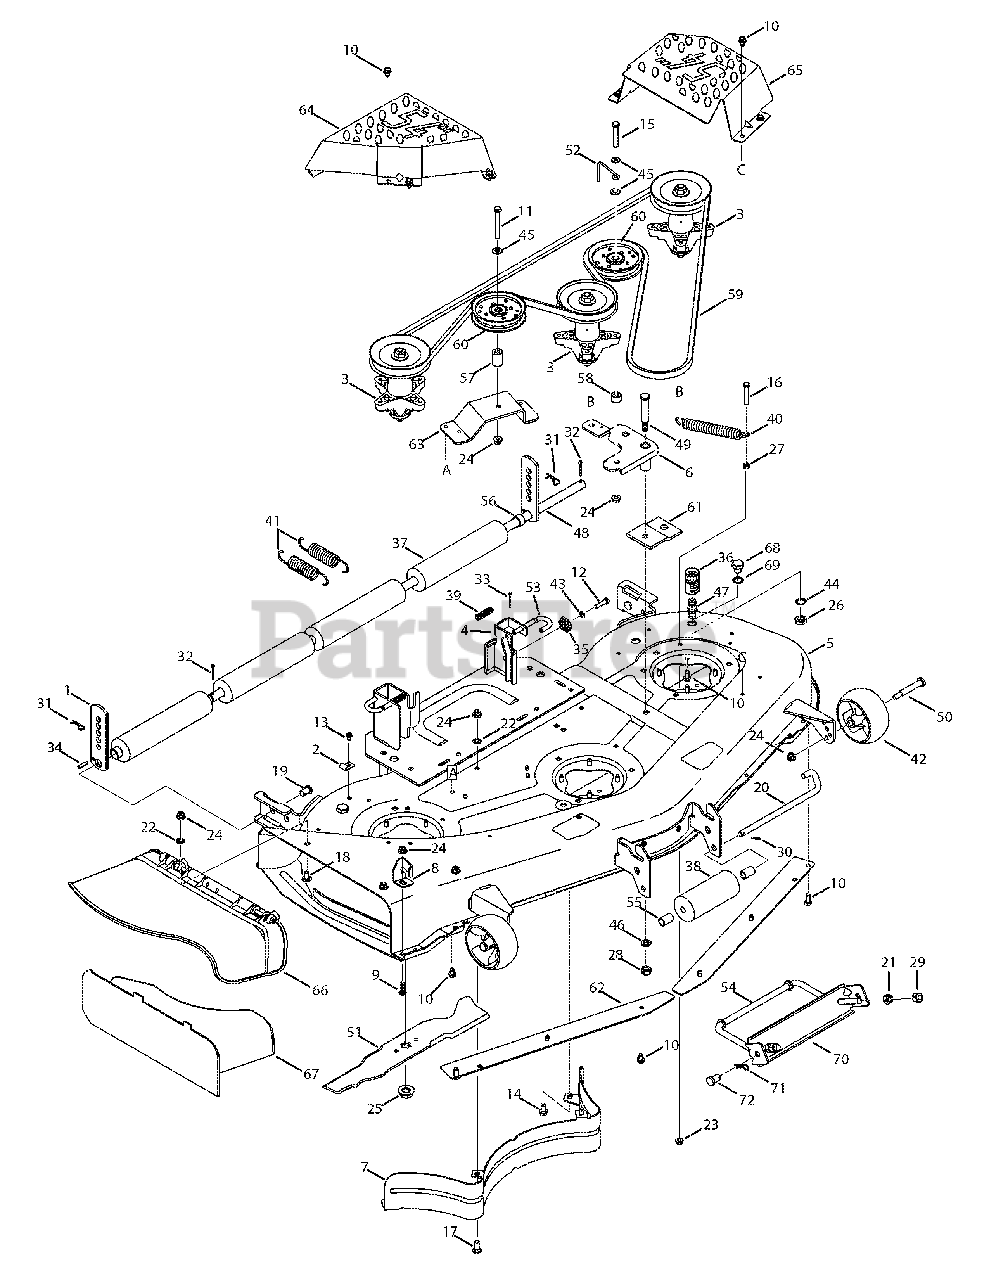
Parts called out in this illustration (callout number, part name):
2	Bracket, Hook, Retainer
3	Spindle Assembly, Pulley
9	Hex Screw 3/8-16 x 1.0
10	Screw, 5/16-18 x 0.750
11	Screw, 3/8-16 x 3.00
12	Hex Screw, 5/16-18 x 1.25
13	Screw, 1/4-20 x.500
14	Screw, 3/8-16 x.750
15	Screw, 3/8-16 x 2.50
16	Hex Screw, 5/16-18 x 2.00
17	Bolt, Carriage, 3/8-16 x 1.0
18	Carriage Bolt 3/8-16 x.75
19	Pin, Clevis,.50 Dia x.78
20	Pin, Roller,.5" Dia x 10.06.
21	Hex Nut, 1/2-13
22	Push Nut Retainer
23	Nut, Flange Lock, 5/16-18
24	Nut, Lock, Flange, 3/8-16
25	Nut, Hex Flange, 5/8-18
26	Hex Nut M16
27	Nut, Hex, 5/16-18, Gr5
28	Nut, Hex Lock, 1/2-13
29	Hex Lock Nut, 1/2-13
30	Pin, Cotter, 3/32 x 1.00
31	Pin, Click,.092 x 1.64
32	Cotter Pin
33	Pin, Cotter, 1/8 x 1.25
34	Pin, Spring 1/4 Dia x 1.00
35	Adjustment, Deck, Gear
36	Water Nozzle Adaptor
37	Roller, Deck
38	Front Roller
39	Spring, Compression
40	Spring, Ext., .94 Dia. x 6.74
41	Spring, Ext., 1.15 Dia. X 5.99
42	Deck Wheel, 5" Dia.
43	Lock Washer
44	Lock Washer, 5/8"
45	Washer, Flat.406 x.875 x.059
46	Lock Washer
47	Deck Wash Water Nozzle
48	Shaft,.750 x.47.12
49	Shoulder Screw
50	Shoulder Screw
51	Blade, 18.50"
52	Idler Belt Keeper Rod
53	Deck Rels. Hndl. Rod,.375 Dia
54	Rod, Deck Adjust
55	Spacer.550 ID x.755 OD x 1.1
56	Spacer,.82 ID x 1.00 OD x.53
57	Spacer,.380 x.900 x 1.313
58	Spacer,.385 ID x.88 x.64
59	Belt, V-Type, B Section
60	Pulley, Idler, 4.25 Dia.
66	Chute Assembly
67	Mulch Plug
68	Plug, Bolt, M16 x 1.5
69	Washer, Flat, .64 x 1.24 x .06
71	Hairpin Clip
72	Clevis Pin, .50 x .78
